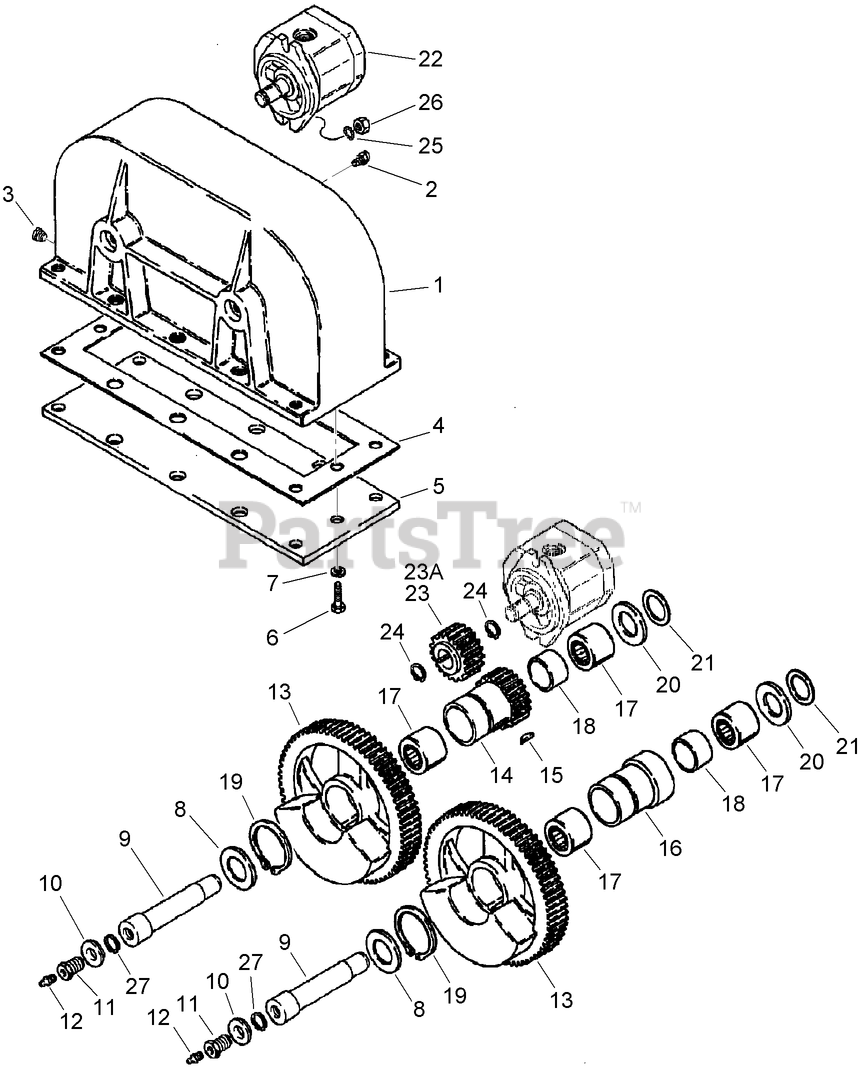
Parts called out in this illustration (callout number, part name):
1	HOUSING - Gearbox
2	BREATHER - 1/8 inch PT, Gearbox Housing
3	PLUG - Hex Socket Headless, 1/8 inch PT
4	GASKET-GEARBOX
5	PLATE - Cover, Bottom
6	SCREW-HH
7	WASHER-Spring Lock, Reg 3/8 ZND
8	WASHER-THRUST
9	PIN-BEARING
10	WASHER-FLAT, STEPPED
11	ADAPTER-LOCATING
12	FITTING - STR Grease 3/16
14	HUB-DRIVE, BEARING
15	KEY-SQUARE
16	HUB-BEARING
17	BEARING-PITCH LINE
19	RING-RETAINING
20	WASHER-10 GAUGE
22	HYD GEAR MOTOR ASM
23	GEAR-MOUNTING, DRIVE
24	RING - External Retaining, No. 68, External, 41/64 inch ID
25	WASHER-TOOTHED, LOCK
26	NUT - Hex, Self-Locking, 7/16 inch NC
27	RING - Internal Retaining, No. 125, 1.388
